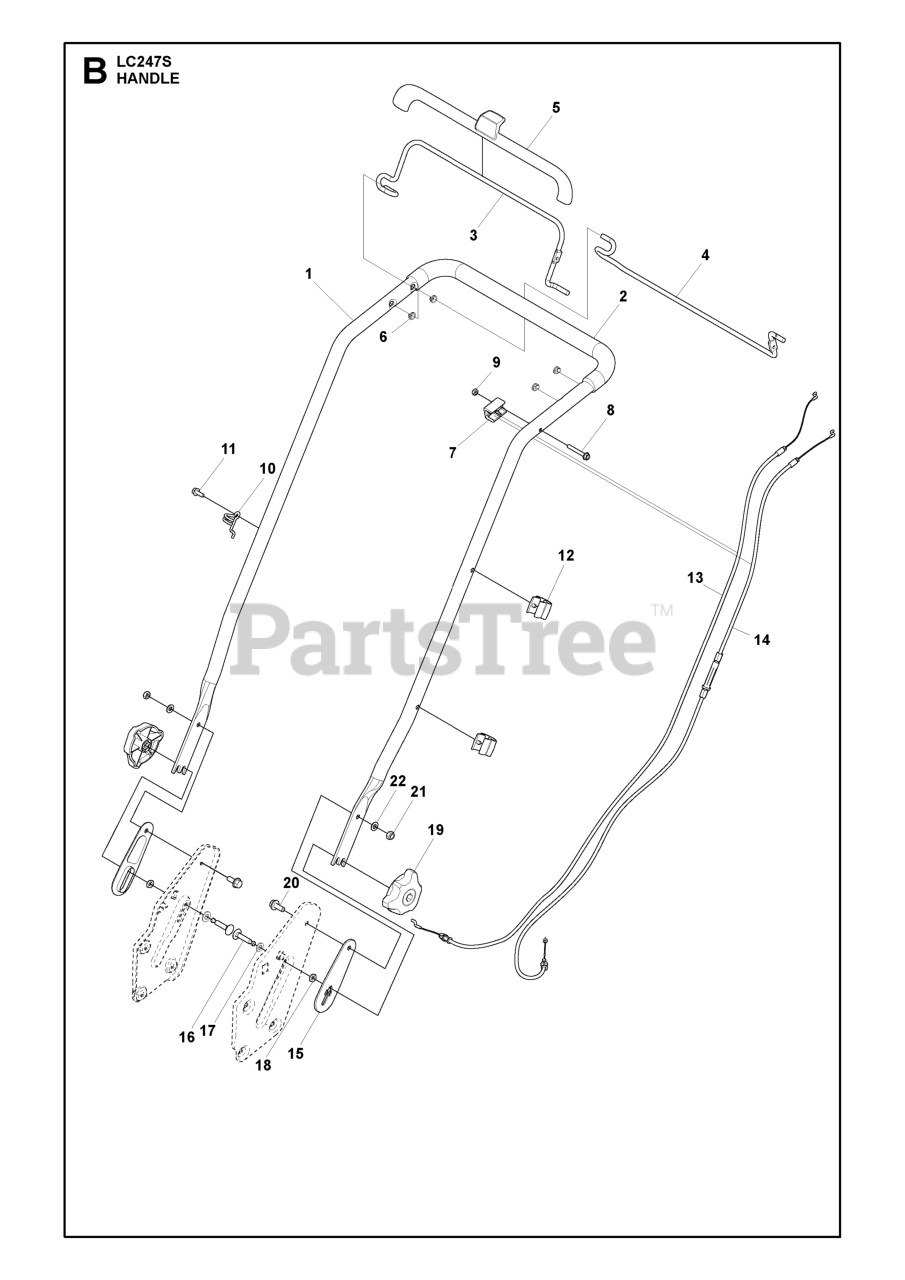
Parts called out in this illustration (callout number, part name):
9	NUT FLANGE - M6
11	SCREW
18	NUT ML6M M8
21	LOCKNUT M8
